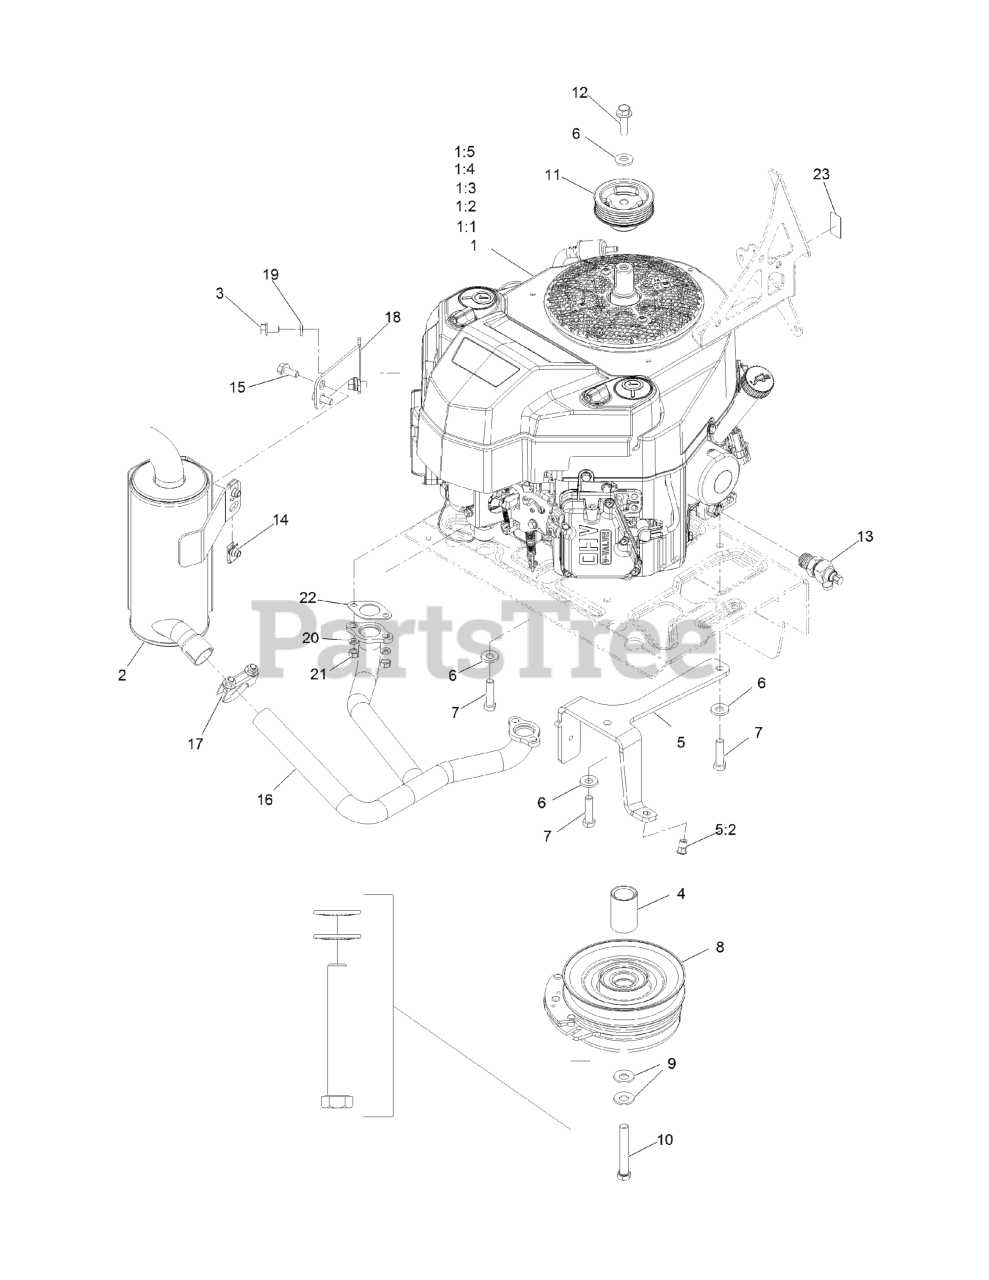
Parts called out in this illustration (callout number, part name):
1:1	Kawasaki 49065-7007 Engine Oil Filter
1:2	Kawasaki 49019-0027 Fuel Filter
1:4	Kawasaki 11013-7046 Foam Pre-Filter
1:5	Kawasaki 11013-0752 Air Filter
2	MUFFLER-VERTICAL KA
3	SCREW-HHF
4	SPACER-CLUTCH
5	ASM-CLUTCH ANCHOR W/INSERT
5:2	NUT-CLINCH,HEX
6	WASHER-BELLEVILLE
7	SCREW-HH
8	CLUTCH 105
9	WASHER-SPRING
10	SCREW-HH W/LOCTITE
11	PULLEY, CRANK
12	Screw-HH, Patch
13	DRAIN-OIL VALVE
15	SCREW-HHF
16	MANIFOLD-VERTICAL KA EXH
17	CLAMP-MUFFLER
18	BRACKET-MUFFLER VERTICAL
19	WASHER-LOCK
20	WASHER-LOCK
22	GASKET-EXHAUST
23	DECAL-10W-50 OIL
